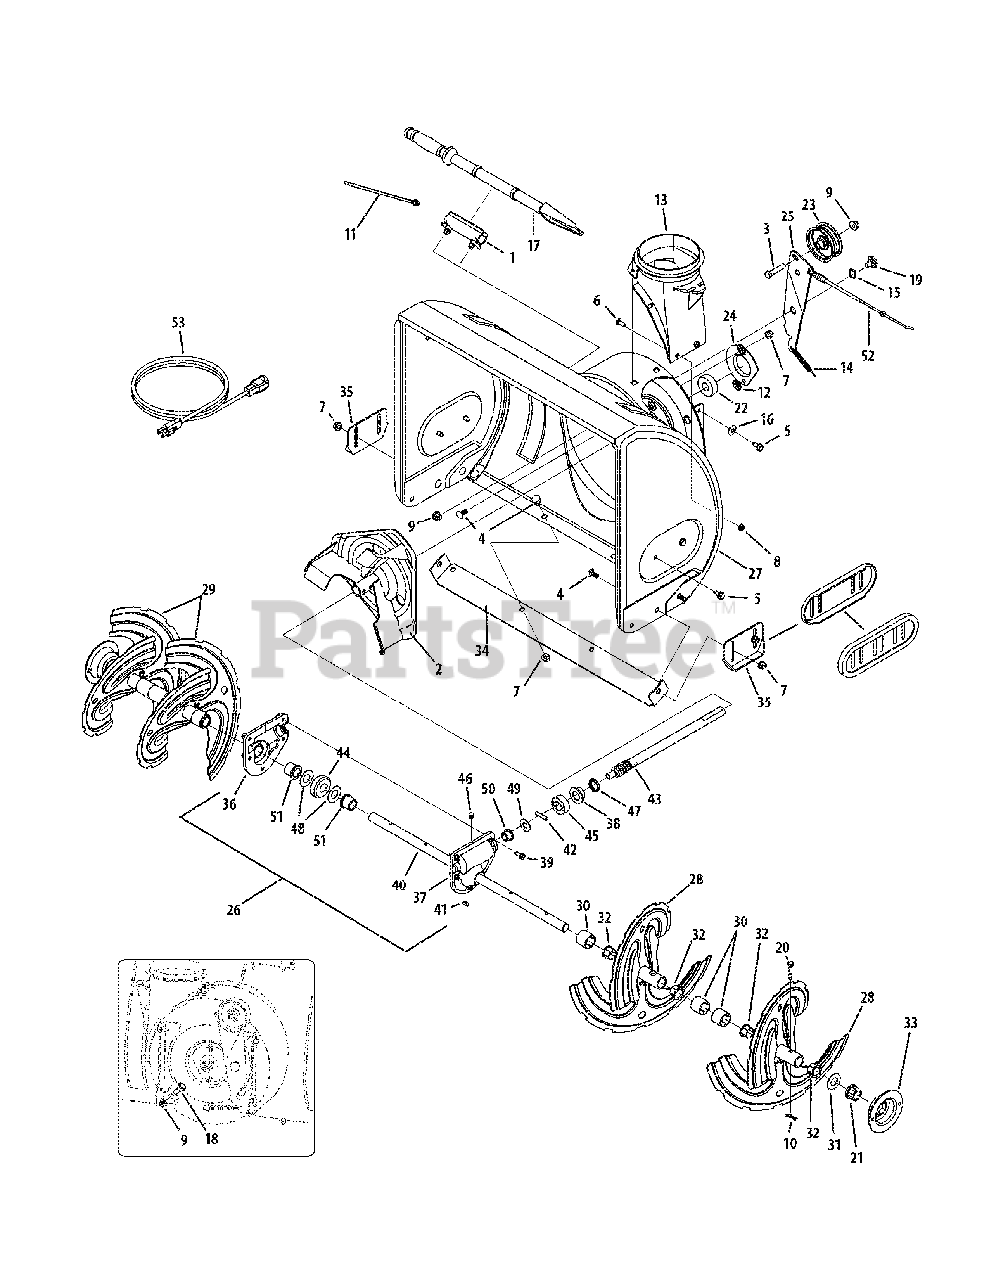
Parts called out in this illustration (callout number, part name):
1	Clean-out Tool Bracket
2	Impeller Assembly, 12" Dia.
3	Hex Screw, 3/8-16, 1.75, Gr5
4	Carriage Bolt, 5/16-18, .750 Gr1
5	Screw, 5/16-18, 0.625
6	Carriage Screw, 1/4-20, .750, Gr5
7	Flange Lock Nut, 5/16-18, Nylon
8	Flange Lock Nut, 1/4-20, Nylon
9	Flaneg Lock Nut, 3/8-16, Nylon
10	Bow-tie Cotter Pin
11	Cable Tie, 3/16 x .05 x 7.4
12	Speed Nut
13	Chute Adapter
14	Extension Spring, .38 OD x 3.6
15	Wave Washer, .625 x .885 x .015
16	Bell Washer, .340 x .872 x .060
17	Clean-out Tool
18	Shoulder Screw, .498 x .34, 3/8-16
19	Shoulder Screw, .625 x .17, 3/8-16
20	Shear Pin, .25 x 1.50
21	Hex Flange Bearing x .75 ID
22	Ball Bearing, .75 ID x 1.85 OD
23	Idler Pulley, 2.75 OD
24	Bearing Housing, 1.85 ID
25	Auger Idler Bracket w/ Brake
26	AUger Gearbox Assembly, 22"
26	Auger Gearbox Assembly, 24"
26	Auger Gearbox Assembly, 26"
26	Auger Gearbox Assembly, 28"
26	Auger Gearbox Assembly, 30"
30	Spacer, 1.25 OD x .75 ID x 1.00
31	Flat Washer, .76 x 1.49 x .06
32	Flange Bushing, .80 ID x .91 OD
36	Auger Housing, RH Reduced
37	Auger Housing, LH Reduced
38	Flange Bearing, .75 x 1.0 x .59
39	Sel-tapping Screw, 1/4-20, 0.750
40	Auger Axle, 22"
40	Auger Axle, 24"
40	Auger Axle, 26"
40	Auger Axle, 28"
40	Auger Axle, 30"
41	Hi-pro Key, 3/16 x 5/8
42	Dowel Pin, .25 OD x 1.2
43	Worm Shaft, .75 OD
44	Worm Gear, 20T
45	Thrust Collar
46	Plug, 1/4 x .437
47	Oil Seal, .75 x 1 x .131
48	Flat Washer, .760 ID x 1.5 OD
49	Flat Washer, .51 x 1.12
50	Flange Bearing, .75 x 1.0 x .925
51	Flaneg Bearing, .75 x 1.00 x .975
52	Auger Clutch Cable, 47.23"
53	Extension Cord, 110V, 3-Prong
